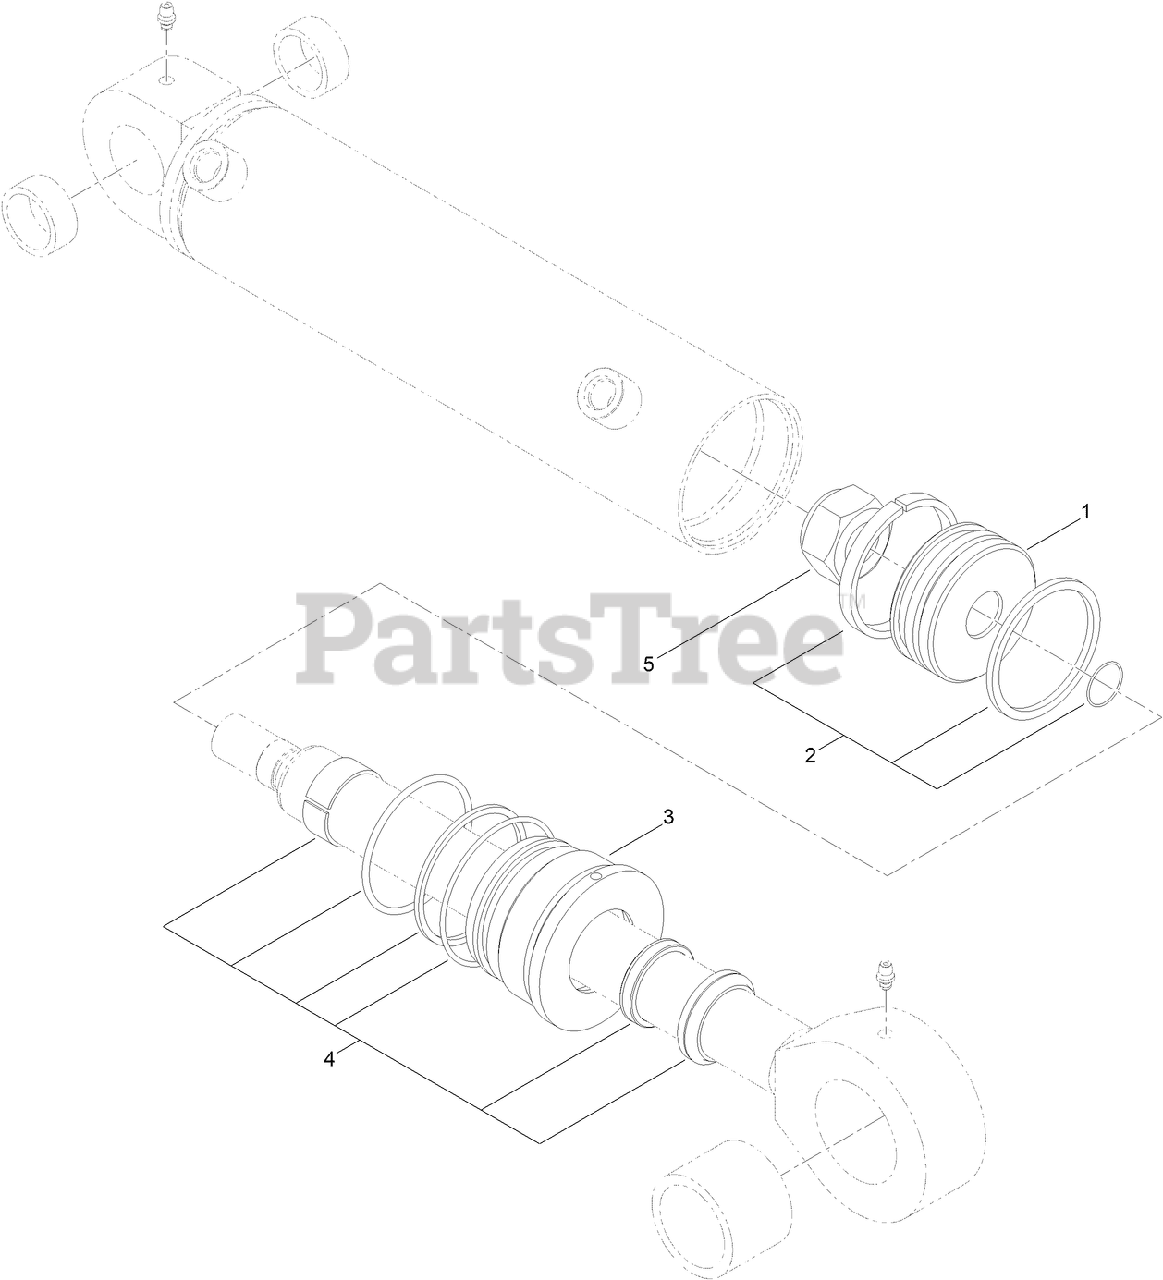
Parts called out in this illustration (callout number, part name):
2	GLAND SEAL KIT
3	PISTON
4	PISTON SEAL KIT
